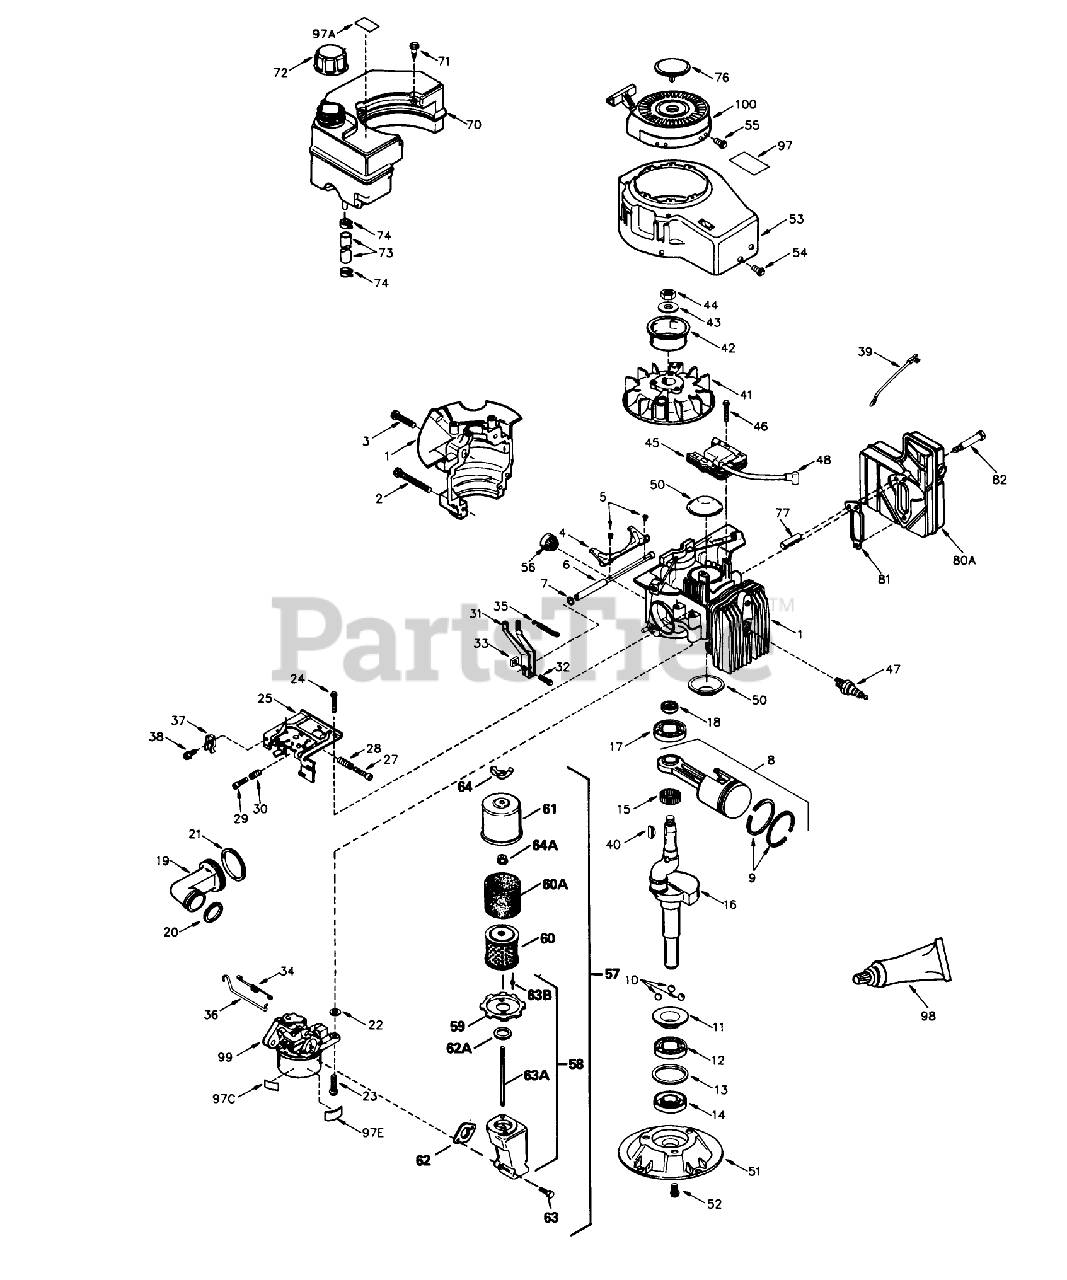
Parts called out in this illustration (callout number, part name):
2	Screw
3	Screw
4	Governor Lever
5	Screw-Shutter
6	Governor Shaft
7	Oil Seal
8	Piston Rod Assy. (Incl. Ref. #9 15)
9	Ring Set-Piston
11	Ring-Slide
12	Ball Bearing
13	Bearing Retainer
14	Oil Seal
15	Bearing-Strip
16	Crankshaft
17	Ball Bearing
18	Oil Seal
19	Intake Pipe Assy. (Incl. Ref. #20 21
20	O Ring
21	O Ring
22	Washer-Bowl Nut
23	Screw-Hex. Washer Hd.
24	Screw (10-24 x 3/8)
25	Control Bracket Assy. (Incl. Ref. #27 thru 30)
27	Screw-Phillips Hd.
28	Spring
29	Screw
30	Spring-Compression
31	Lever-Governor
32	Screw
33	Nut-Lock
34	Spring-Throttle Link
35	Spring-Governor
36	Link-Governor
37	Conduit
38	Screw-Hex. Hd.
39	Wire-Ground
40	Key-Flywheel
41	Flywheel
42	Cup-Starter
43	Washer-Belleville
44	Nut-Flywheel
45	Solid State
46	Screw
47	Spark Plug-Resistor (R C J 8Y)
48	Cover-Spark Plug
50	Cover-Port
51	Adapter
52	Screw-Hex. Washer Hd.
53	Housing-Blower
54	Screw
55	Screw, Hex Hd.
56	Filter-Fuel
57	Dual Upright Canister Air Cleaner Kit (Incl. Ref. #58, 60, 60A, 61, 62, 63, 64 97B)
58	Elbow Assy., Air Cleaner (Incl. Ref. #59, 62A, 63A 63B)
59	Bracket-Air Cleaner
60	Filter, Air Cleaner (incl. Ref. #64A)
60A	Filter-Pre-Air
61	Body, Air Cleaner
62	Gasket-Air Cleaner
62A	Gasket, Air Cleaner
63	Screw, Fil hd.
63B	Pop Rivet (Can be purchased locally.)
64	Nut-Wing
64A	Nut Lockwasher
70	Fuel Tank Assy.
71	Screw-Hex. Hd.
72	Cap-Fuel
73	Line-Fuel (8.62)
74	Clamp-Line, Fuel
76	Plug Starter
80A	Muffler
81	Exhaust Gasket
82	Screw-Hex. Hd.
97	Decal-Name
97A	Decal-Fuel Mixture
97C	Decal-Primer
97E	Decal-Instruction
98	Gasket Eliminator
99	Carburetor (Incl. Ref. #20)
100	Starter-Rewind
